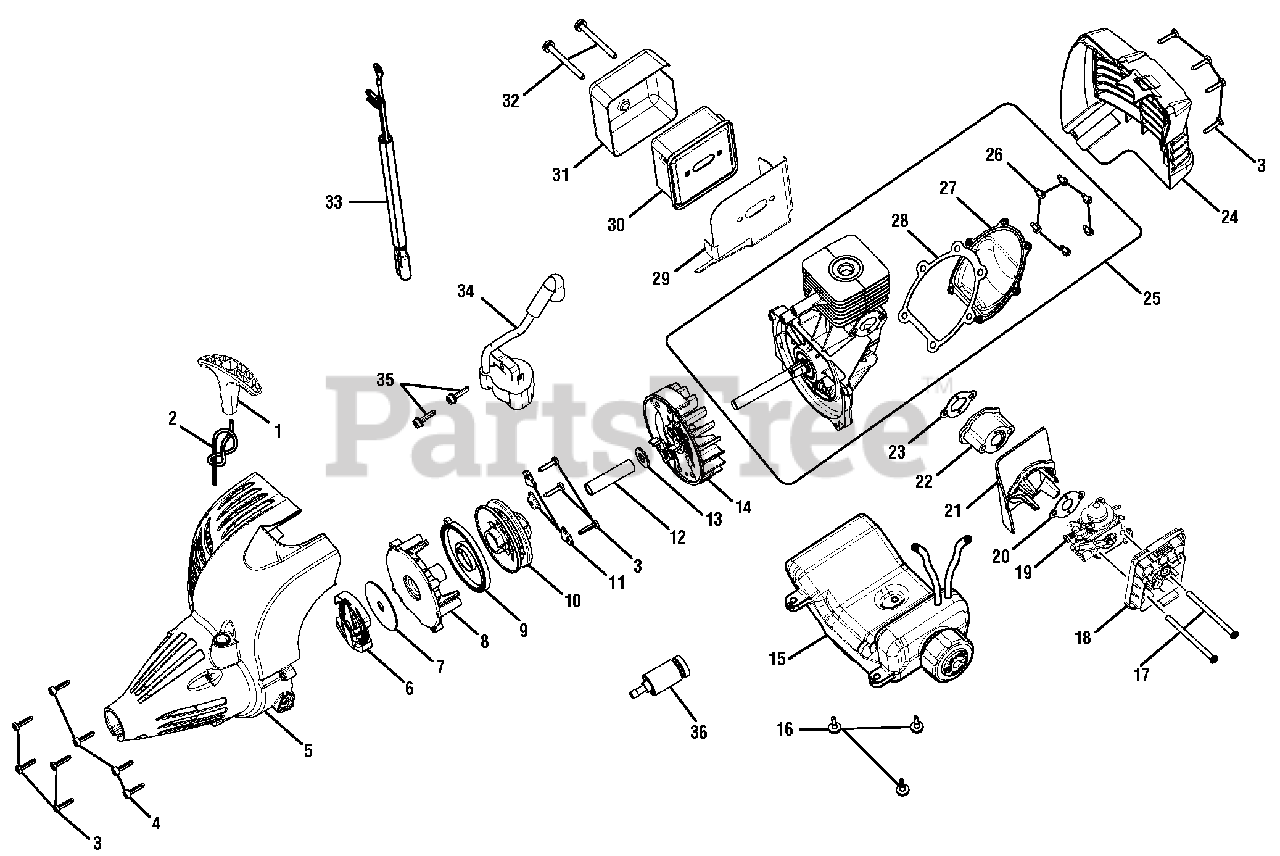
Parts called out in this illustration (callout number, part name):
1	Starter Grip
2	Starter Rope (42 in.)
3	Screw (M4 x 18 mm)
4	Screw (M4 x 16 mm)
5	Starter Housing Assembly
6	Clutch Assembly
8	Starter Baffle
9	Spring and Container
10	Easy Starter Assembly
11	Pulley Retainer
12	Spacer Tube
13	Washer
14	Flywheel Assembly
15	Fuel Tank and Cap Assembly
16	Screw (M4)
17	Bolt (M5 x 76 mm)
18	Air Box Base
19	Carburetor Assembly
20	Outer Heat Dam Gasket
21	Air Baffle
23	Inner Heat Dam Gasket
24	Rear Housing
25	Short Block Assembly
26	Screw (M4 x 12 mm)
27	Crankcase Cover
28	Crankcase Cover Gasket
29	Muffler Gasket
30	Muffler Assembly
31	Muffler Housing
32	Muffler Bolt (10-24 x 2-1/8 in.)
33	Electrical Lead Wire Assembly
34	Ignition Module
35	Screw (M4 x 19 mm)
36	Fuel Filter
